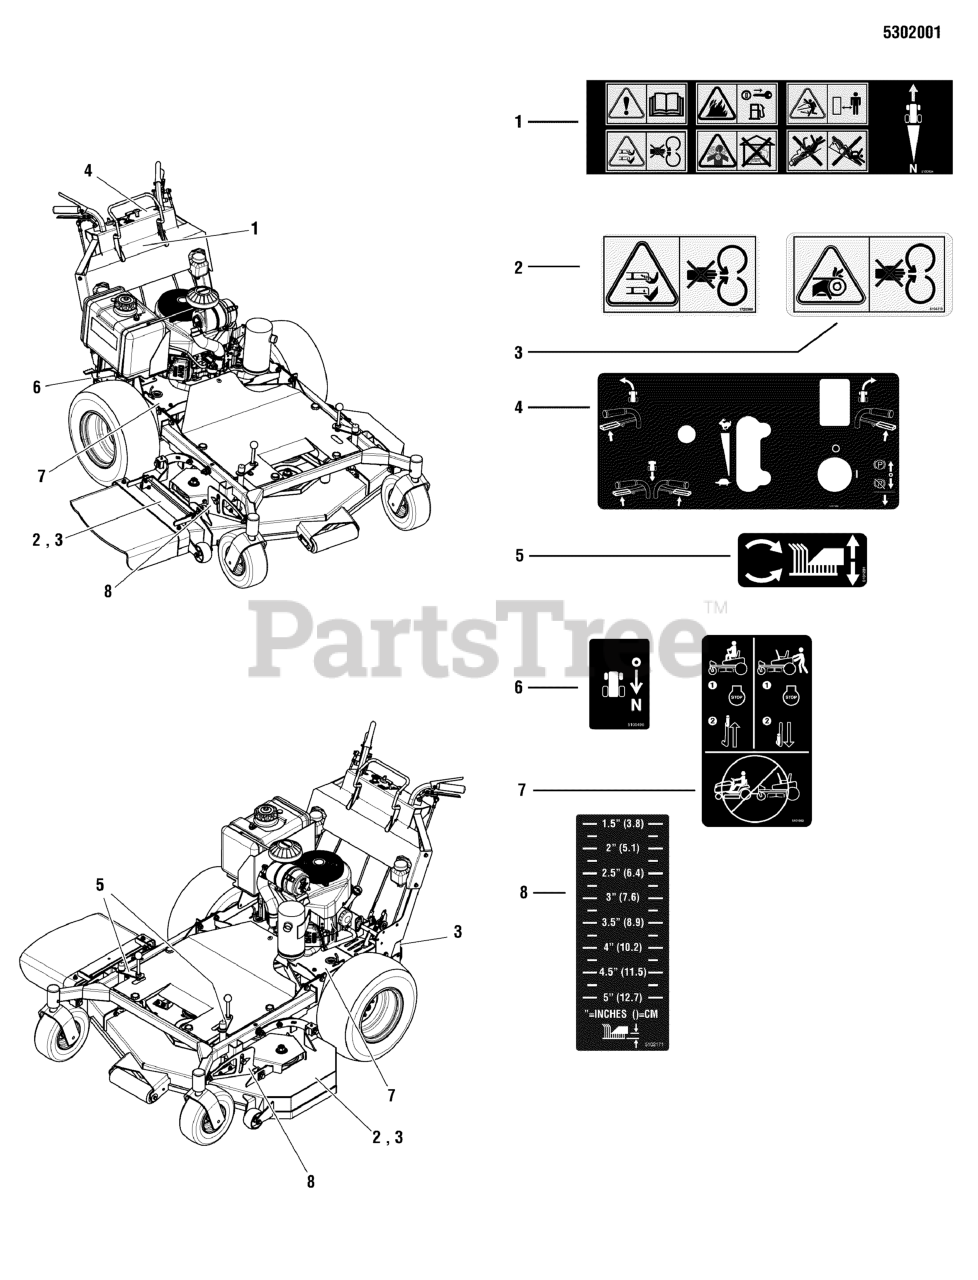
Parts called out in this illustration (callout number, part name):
1	DECAL, CCW, CE
2	DECAL-DANGER ROTATING BLADE SYMBOLS
3	DECAL, CE DANGER
5	DECAL, CUT HEIGHT, SPDD
6	DECAL, PEDAL
7	DECAL, TRANSAXLE RELEASE
8	DECAL, DECK HEIGHT, SW30
